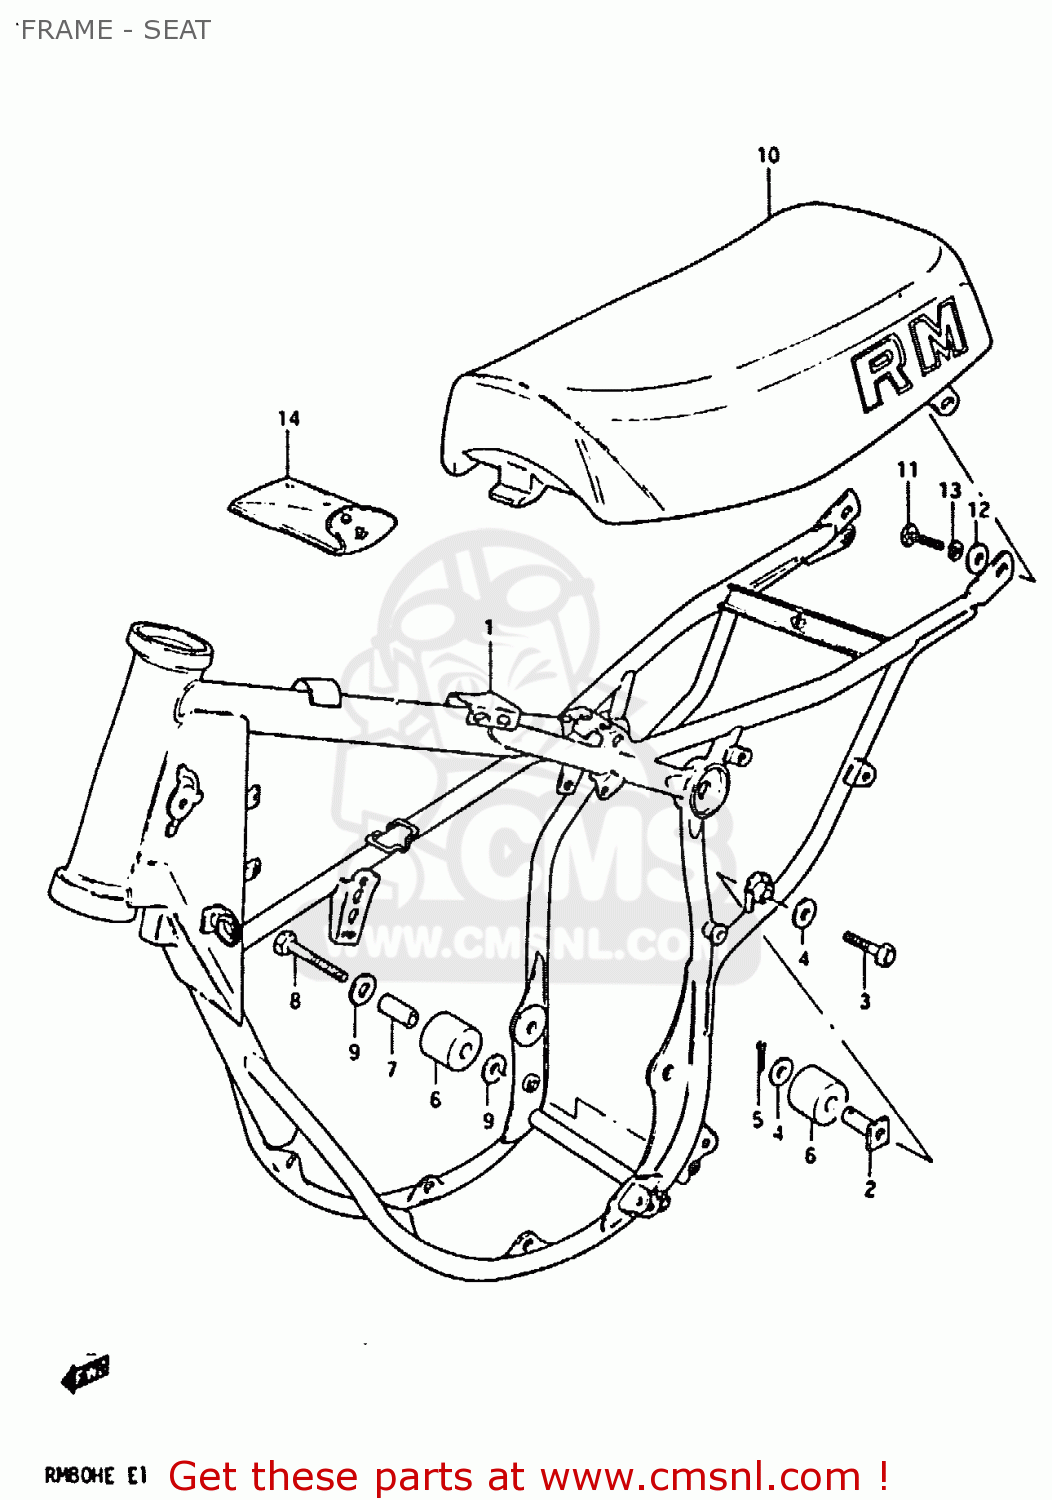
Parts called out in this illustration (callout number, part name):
1	FRAME (BLUE)
2	BOSS,CHAIN CONTROL
3	BOLT
4	WASHER
5	PIN 25X20
6	ROLLER,CHAIN LENGTH CONTROLLER
7	SPACER (6.5X10.5X29)
8	BOLT
9	WASHER
10	SEAT ASSY (BLUE)
11	BOLT
12	WASHER
13	LOCK WASHER
14	TOOL SET
